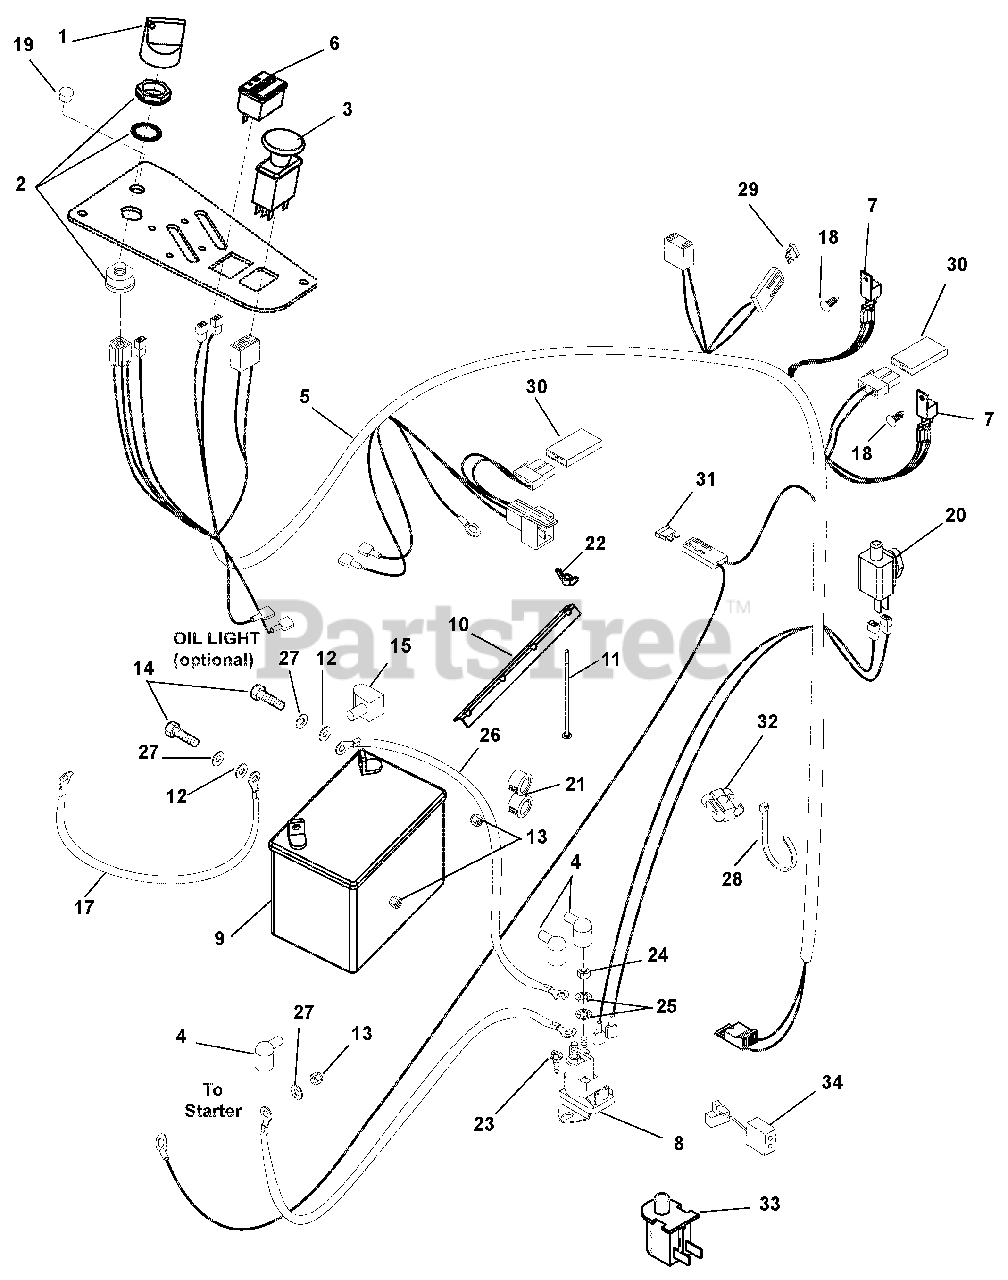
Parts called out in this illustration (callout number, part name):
1	KEY, W/ SHIELD
2	SWITCH, IGNITION
3	SWITCH, CLUTCH
4	BOOT, BATTERY TERMINAL-RED
5	HARNESS - WIRE
5	HARNESS,WIRE(SEALED SOLENOID)
6	METER, HOUR W/MAINTENANCE
7	RELAY,SEALED W/DIODE
8	SOLENOID, HP RTV
8	SOLENOID, STARTER (SEALED)
9	BATTERY, 300 CCA 10U1L
10	HOLD DOWN
11	BLT-RDHDSQNK .25-20X7.50 GR2YZ
12	@WSHR-FL-STL.281X.62X.065 YWZC
13	@NUT-HEX .25-20 YWZC
14	@BLT-HEX .25-20X.75 GR5 YWZC
15	INSULATOR
16	CABLE-POSITIVE BATTERY 9.00"
16	CABLE, POS W/(2)1/4 RING 9.0LG
17	CABLE-NEGATIVE BATTERY 24.00"
18	RIVET, .25 NYLON PANEL
19	PLUG-HOLE .50 DIA
20	SWITCH, SINGLE POLE N.O.
21	BUSH, PANEL SNAP .687X.875X.56
22	NUT-LK WING .250-20 YWZC
23	@SCR-TAP .25-20X.50 HWH TR YWZ
24	NUT-JAM .31-24 YWZC
24	NUT-HEX M6X1.0 YWZC
25	@WSHR-LK-EXT.326X.599X.031YWZC
26	CABLE, STARTER .31X23.00X.31
26	CABLE,POS W/(2)1/4 RING 21.5LG
27	@WSHR-LK .25X.062 REG YWZC
28	CABLE TIE LG 5-1/2
29	FUSE 20AMP
30	DIODE, CONNECTOR SHELL
31	FUSE-25 AMP ATC TYPE
32	CLIP,T,.31-.38,
33	SWITCH- SNAP MTG N.O.
34	HARNESS ADAPTER, CLUTCH
